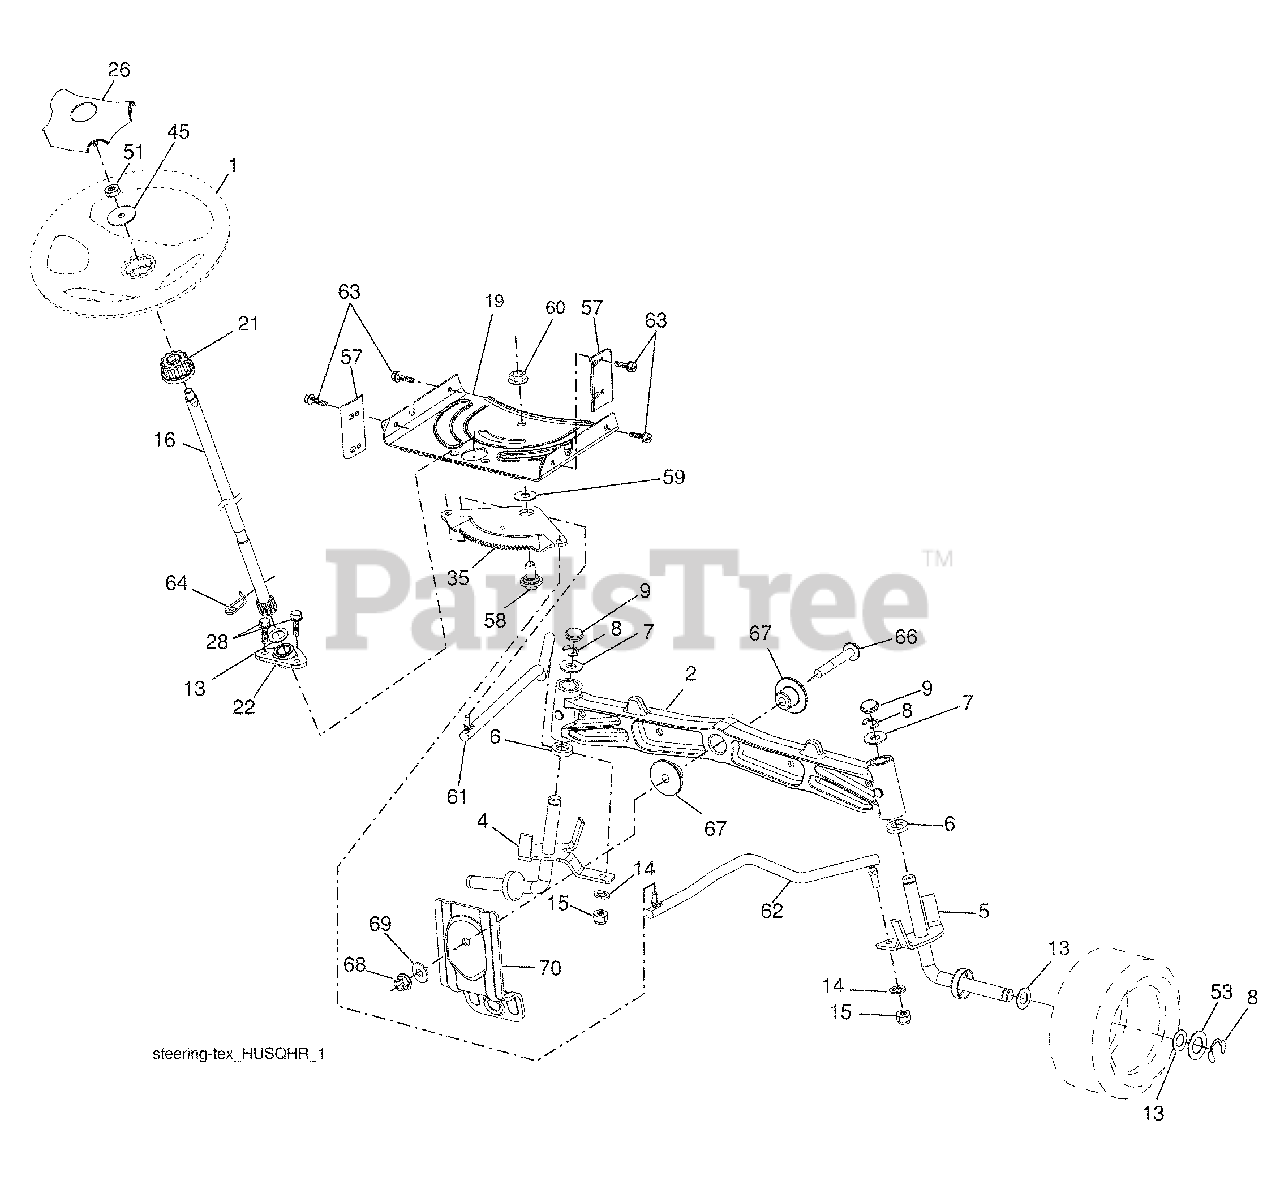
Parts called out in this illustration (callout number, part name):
1	Wheel, Steering
2	Axle Cast Iron
4	Spindle Asm., LH
5	Spindle Asm., RH
6	Washer, Thrust
7	Washer 25/32 x 1-5/8 x 16 Ga.
8	Ring, Klip #T5304-75
9	Cap, Spindle
13	Washer 25/32 x 1-1/4 x 16 Ga.
14	Washer, Lock Hvy Hlcl Spr 3/8
15	Nut, Crown Lock 3/8-24 unf
16	Shaft Steering
19	Plate Steering
21	Adapter, Wheel Steering
22	Bushing, Strg. Blk
26	Insert, Wheel Steering
28	Screw 3/8-16 x 3/4
35	Gear, Sector Plate
45	Washer 9/16 ID x 2-3/8 OD 12 Ga.
51	Nut Hex Jam Toplock 1/2-20 unf
53	Washer Hardened .793 x 1.637 x .060
57	Bracket Upstop
58	Bolt Shoulder Sector Pivot CFM
59	Washer Thrust Sector Steering
60	Nut Flange Lock 5/8-11
61	Draglink, LH
62	Draglink, RH
63	Screw 5/16-18 x 3/4
64	Retainer Clip Spring Steering
66	Bolt Hex Fghd 7/16-14 x 3 Serr
67	Bushing PM Front Axle
68	Nut Lock Flange 7/16-14 Gr. 5
69	Washer 1.5 x .505 x .118
70	Bracket Deck Susp. Front
